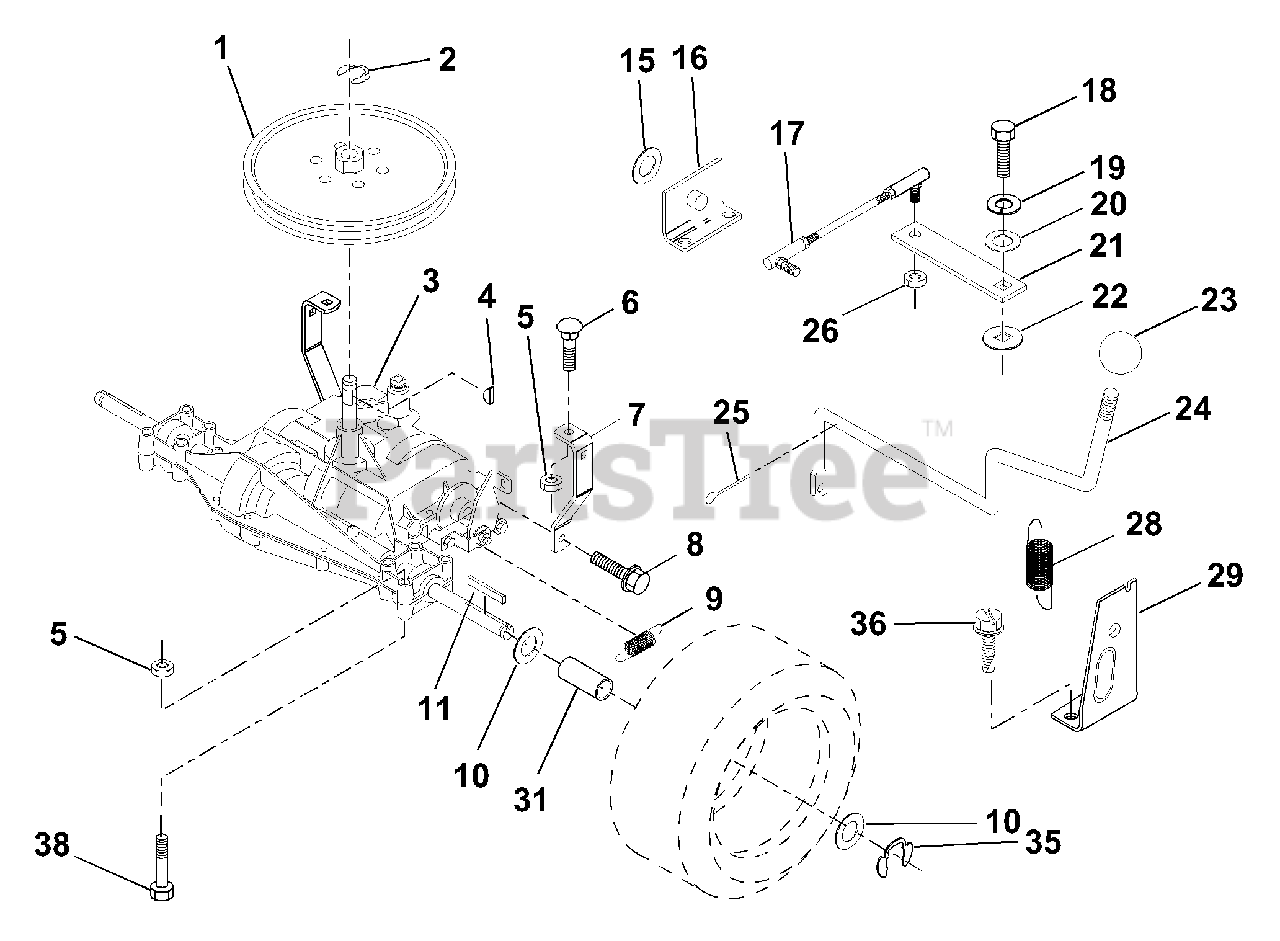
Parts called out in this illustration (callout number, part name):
2	Ring, Retainer
4	Key, Woodruff #9
5	Nut, Crownlock 5/16-18
6	Bolt, Carriage 5/16-18 UNC x 3/4
7	Strap, Torque
8	Screw 5/16-18 x 3/4
9	Spring, Brake
10	Washer 25/32 x 1-1/4 x 16 Ga.
11	Key, Square
15	Washer 17/32 x 1 x 16 Ga.
16	Support Handle Shift LH
17	Link, Shift
18	Bolt, Fin Hex 1/4-28 UNF x 3/4 Gr. 8
19	Washer, Lock 1/4
20	Washer 9/32 x 3/4 x 10 Ga.
21	Arm, Shift
22	Washer, Shift Plate
23	Knob, Rd 1/2-13
25	Pin, Cotter 1/8 x 1
26	Locknut 5/16-24 UNF
28	Extension, Spring
29	Support Handle Shift RH
31	Spacer Axle
36	Screw, Thd Cut 1/4-20 x 1/2
38	Bolt Hex Flghd 5/16-18 x Gr. 5
